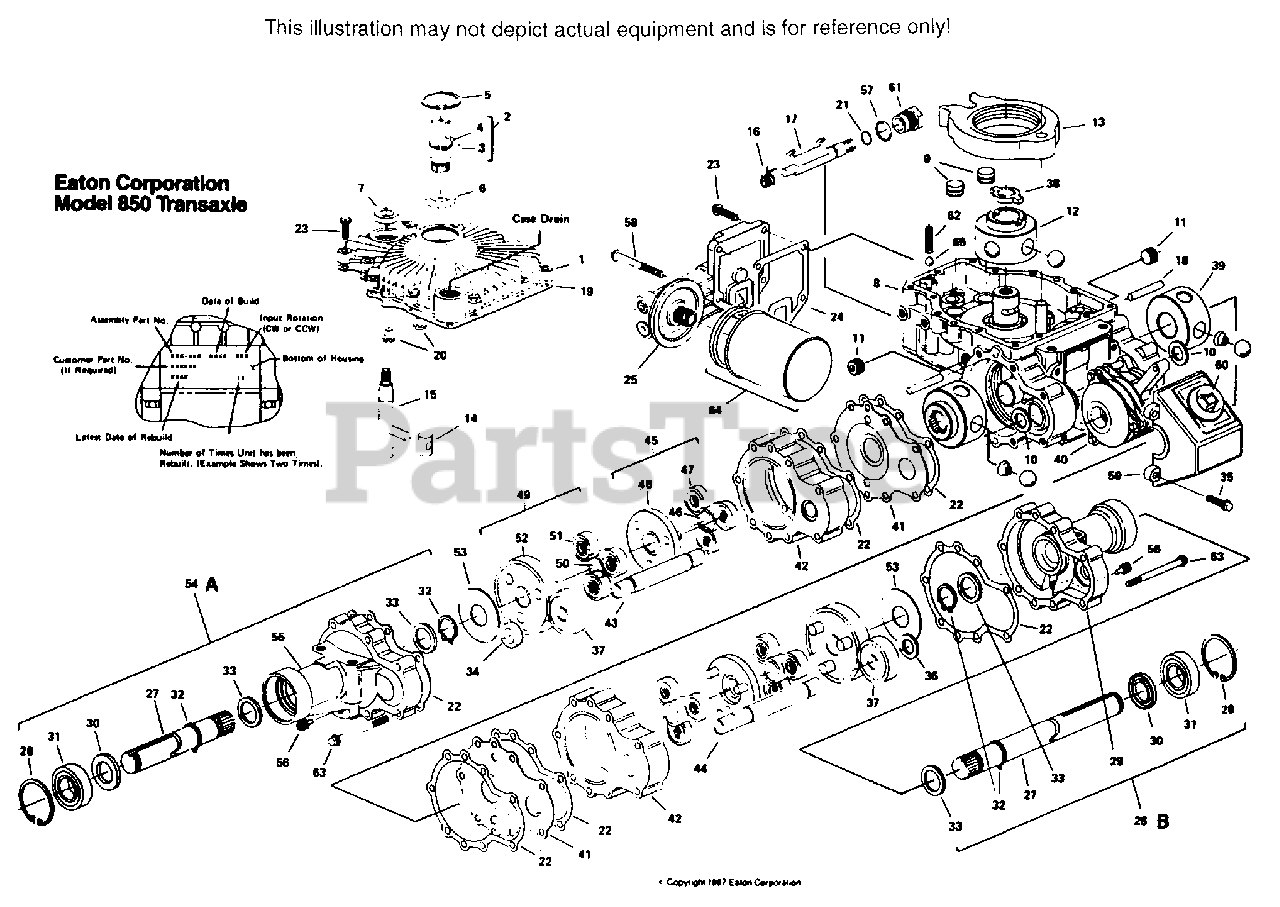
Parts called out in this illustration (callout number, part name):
1	COVER SUBASSEMBLY S/A
3	BEARING, INPUT SHAFT
4	RING, RETAINING, EXTERNAL
5	RING, RETAINING, INTERNAL
6	SEAL, INPUT SHAFT
7	SEAL, CONTROL SHAFT
9	PISTON, DAMPENING, S/A
10	SEAL, BRAKE SHAFT
11	PLUG, SOCKET PIPE
12	PUMP ROTOR-BALL-PIN, S/A
13	CAM RING, S/A
14	INSERT
15	CONTROL SHAFT, S/A
16	SPRING, DUMP VALVE
17	BRACKET, DUMP VALVE(ALUMINUN SHAFT)
18	DOWEL
19	GASKET, COVER
20	BUTTON
21	"O"-RING, DUMP VALVE BRACKET
22	GASKET, AXLE HOUSING
23	SCREW, 1/4-20 HEX FLANGE
24	GASKET, FILTER BASE OR PORT PLATE
25	FILTER BASE, S/A
26	AXLE HOUSING, S/A SIDE B(FOR 850-030 &
27A	SHAFT, AXLE SIDE A
27B	SHAFT, AXLE SIDE B(FOR 850-026 ONLY)
28	RETAINING RING, INTERNAL
29	HOUSING, AXLE B
30	SEAL, AXLE SHAFT
31	BEARING, AXLE SHAFT
32	RETAINING RING
33	WASHER, THRUST
34	SPACER, THICK
35	SCREW, 1/4 SELF TAPPING
36	SPACER, THIN
37	BRAKE GEAR
38	DRIVE
40	PARKING BRAKE ASSY.
41	PLATE, WEAR
43	BRAKE SHAFT - SIDE A
44	BRAKE SHAFT - SIDE B
51	SECONDARY CARRIER, A&B S/A
53	WASHER, THRUST
54	AXLE HOUSING, S/A SIDE A(FOR 850-030 &
55	HOUSING AXLE A
56	PLUG, MAGNETIC
57	"O"-RING, DUMP VALVE
58	SCREW, 1/4-20 HEX FLANGE
59	COVER, PARKING BRAKE
60	BOOT, DUST
61	DUMP VALVE NUT
62	SPRING, RELIEF VALVE
63	SCREW, 1/4-20 HEX FLANGE
64	FILTER, W/SEAL
